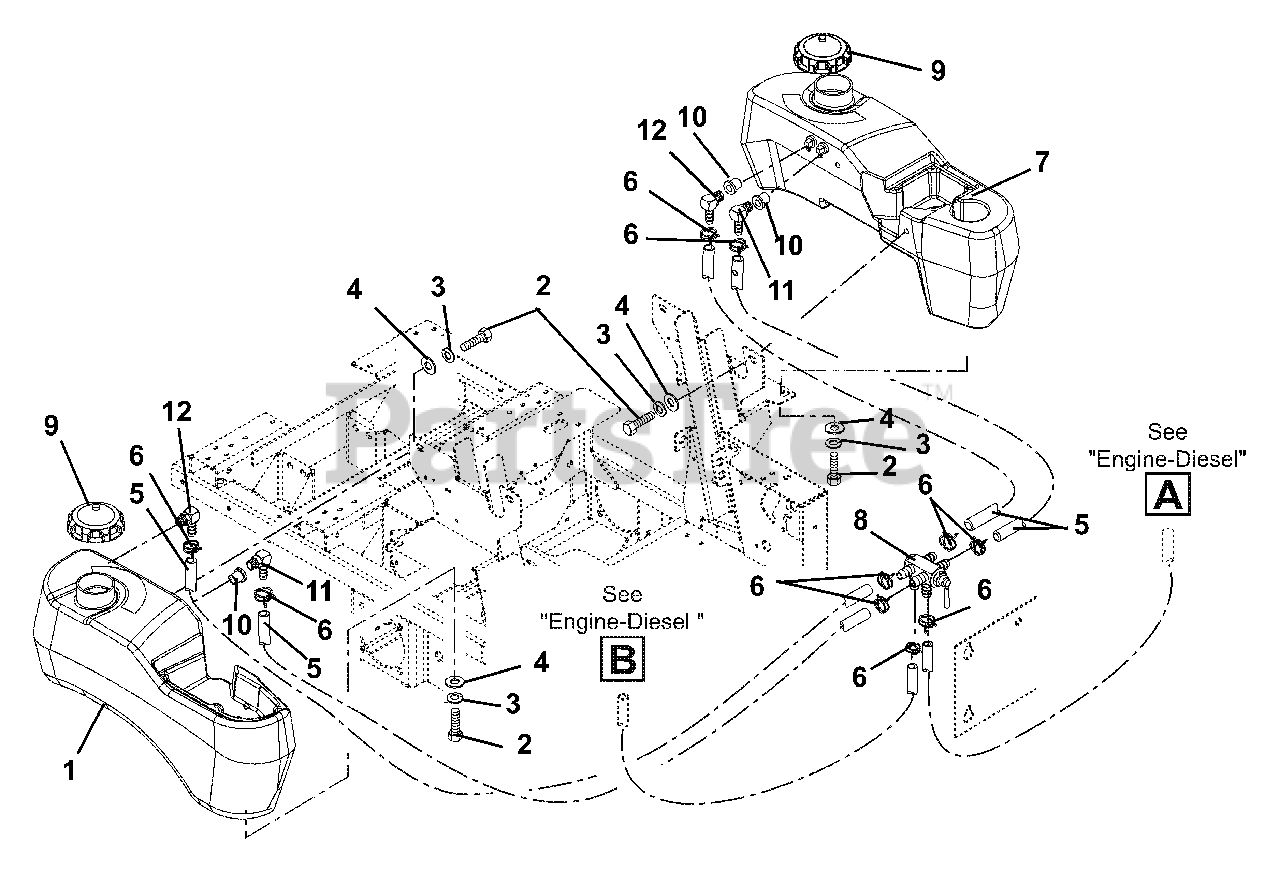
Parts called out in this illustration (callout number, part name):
1	Tank, Fuel-Right Hand
2	Bolt, Hex .31-18 x .75 Grade 5
3	Washer, Locking .31 x .078
4	Washer, Flat Steel .38 x .875 x .083
5	Hose, .31 ID
6	Clamp, Hose Wire .52/.55
7	Tank, Left Hand Fuel (EYE-Q) 200 Series-EFI
8	Valve, Fuel
9	Cap, Fuel
11	Fitting, Tank
12	Fitting, Tank
